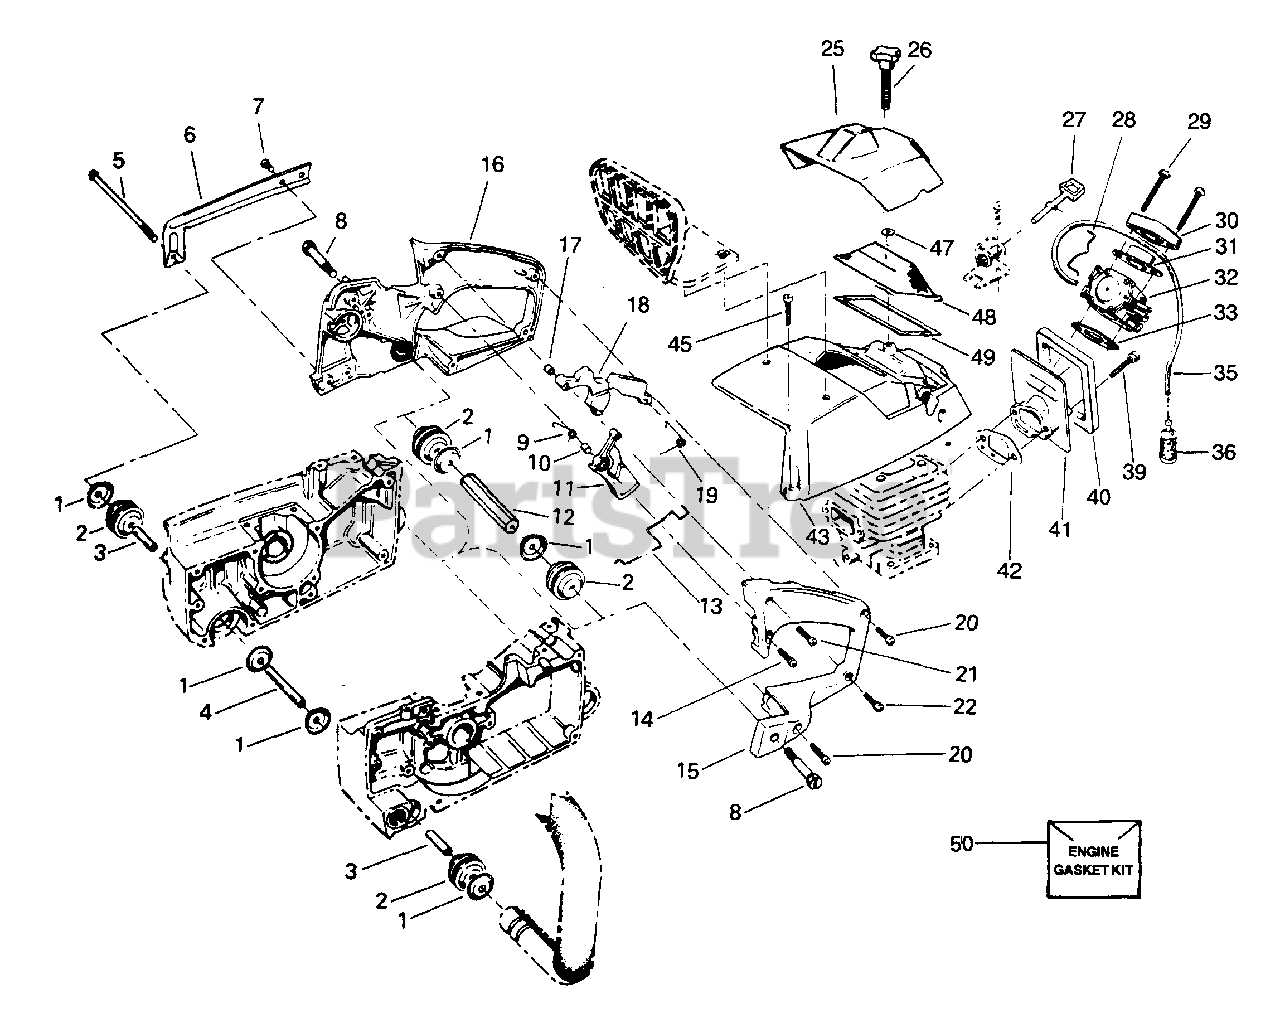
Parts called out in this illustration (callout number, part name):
1	Cup Isolator
1	New Style Rear Isolation System
1	Old Style Rear Isolation System
2	Isolator - Powerhead Rear Handle
2	Use on Guide Bar Powerhead
2	Use on Bow Guide Powerhead
3	Spacer - Front Handlebar Isolator Mount
4	Spacer - Front Handlebar - Center - Isolator Mount
5	Screw - 1/4-20 x 5-5/16
6	Handle Brace
7	Screw - 1/4-20 x 3/4 Button Hd.
8	Shoulder Screw 1/4-20 - Isolator Mount
9	Spring - Trigger
10	Bushing - Trigger
11	Throttle - Trigger
12	Spacer - Isolator (Center)
13	Wire Throttle
14	Shoulder Screw - 10-24 x 5/8 - Fil. Hd. - Throttle Trigger
15	Rear Handle Left
16	Rear Handle Right
17	Bushing - Throttle Lock
18	Throttle Lock
19	Spring - Throttle Lock
20	Screw - 10-24 x 13/16 - Fil. Hd.- Rear Handle
21	Screw - 8-32 x 13/16 - Fil. Hd. - Rear Handle Throttle Lock
22	Screw - 8-32 x 9/16 - Fil. Hd. - Rear Handle Lower
25	Cover - Carburetor
26	Knob - Carburetor Cover
27	Choke Rod
28	Wire - Choke
29	Screw - 10-24 x 11/16 - Fil. Hd. Carburetor to Adaptor
30	Seal - Adaptor Shield
31	Bracket - Carburetor Seal
32	Carburetor
33	Gasket - Carburetor to Adaptor
35	Fuel Line
36	Fuel Pick-up Ass'y.
39	Screw - 10-24 x 13/16 - Hex Hd. Adaptor to Cylinder
40	Seal - Carburetor Adaptor
41	Carburetor Adaptor
42	Gasket - Adaptor to Cylinder
43	Cylinder Shield
45	Screw - 10-24 x 5/8 - Fil. Hd. Cylinder Shield to Crankcase
47	Retainer - Carb. Cover Knob
48	Air Filter
49	Gasket - Air Filter
50	Kit - Engine Gasket
